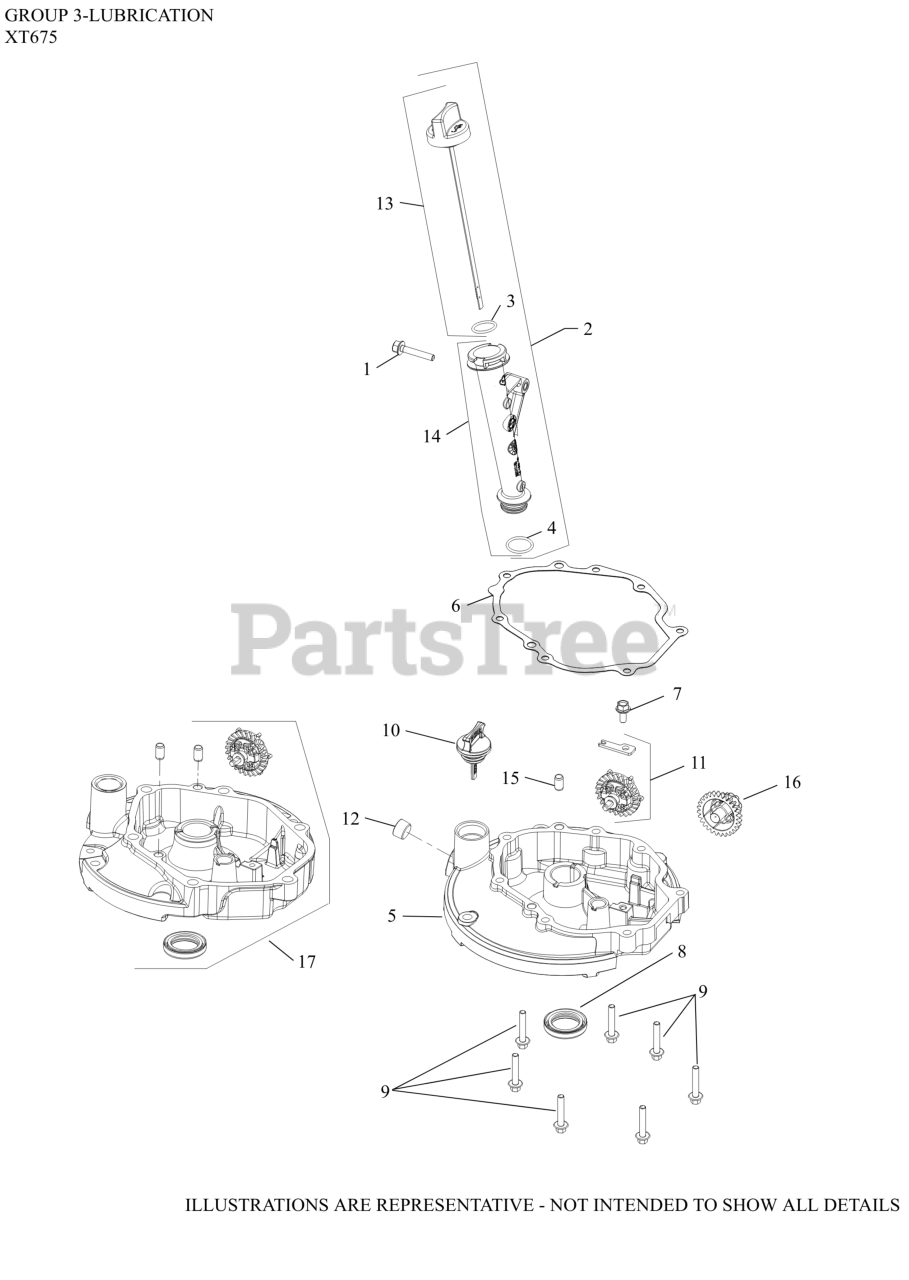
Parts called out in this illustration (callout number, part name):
1	SCREW, HEX FLANGE (M6)-(#25086435S)
2	KIT, DIPSTICK AND TUBE-(#1412320S)
3	O-RING (CAP)
4	O-RING, OIL FILL TUBE
6	GASKET, OIL PAN
9	SCREW, HEX FLANGE (M6)-(#25086434S)
11	GEAR ASSEMBLY, GOVERNOR
13	CAP, DIPSTICK ASSEMBLY
14	TUBE ASSEMBLY, OIL FILL
15	PIN, DOWEL (8MM)
16	GOVERNOR ASSEMBLY-USE 17 310 08-S
